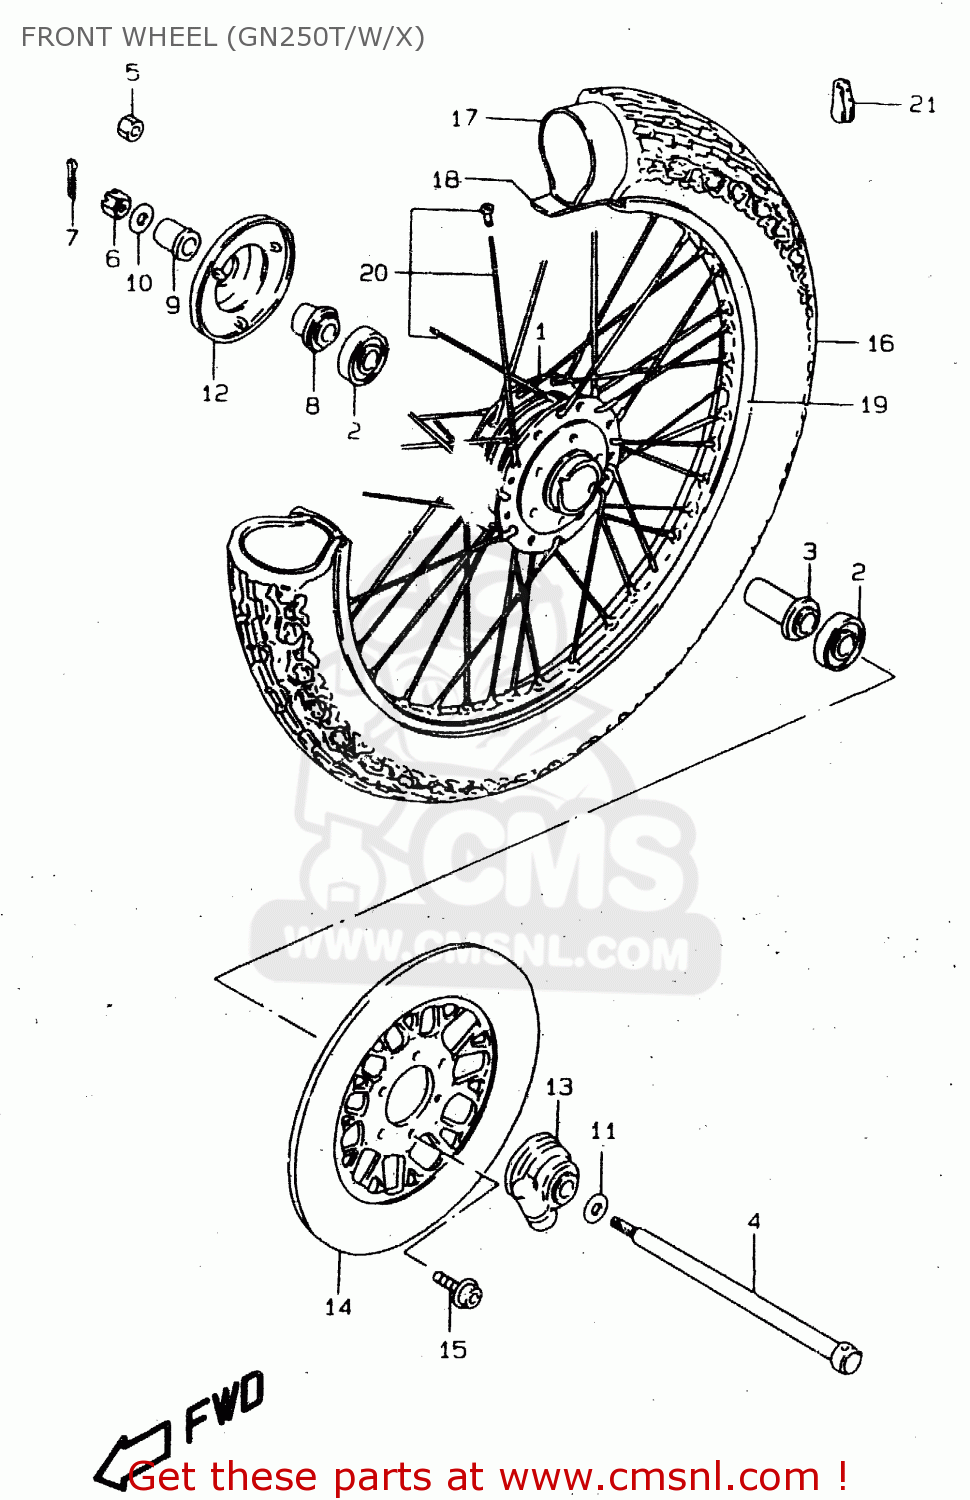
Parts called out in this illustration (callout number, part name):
1	HUB,FR WHEEL
2	BEARING
3	SPACER,FR HUB BEARING
4	AXLE,FR
5	NUT
6	NUT
7	COTTER PIN
8	SPACER,FR AXLE,R
9	SPACER
10	WASHER
11	WASHER(15.5X26X2.3)
12	COVER,FR HUB,R
13	BOX ASSY,SPEEDOMETER GEAR
14	DISC,FR BRAKE
15	BOLT(8X30)
16	TIRE,FRONT 3.00 S18
17	TUBE,INNER
18	PROTECTOR,INNER TUBE
19	RIM,FR WHEEL
20	SPOKE ASSY,FR WHEEL
21	BALANCER,WHEEL (B)
